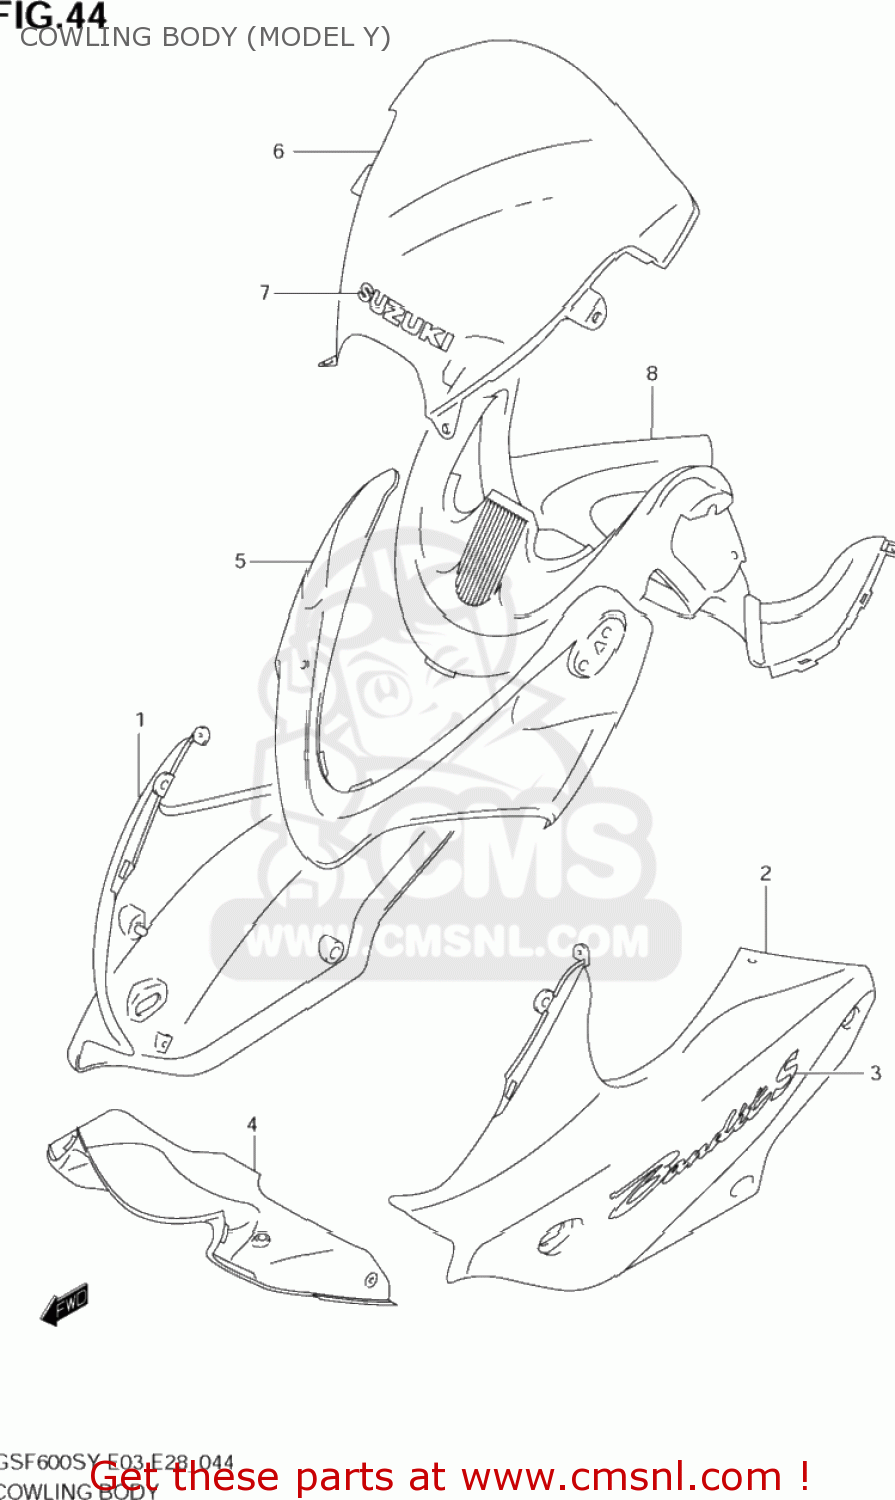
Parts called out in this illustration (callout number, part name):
1	COWLING ASSY,SIDE,R
2	COWLING ASSY,SIDE,L
3	EMBLEM,COWLING SIDE
4	COWLING,CTR(RED)
5	COWLING,FR
6	WINDSCREEN ASSEMBLY (SILVER)
7	EMBLEM,SUZUKI
8	PANEL COMP,METER
